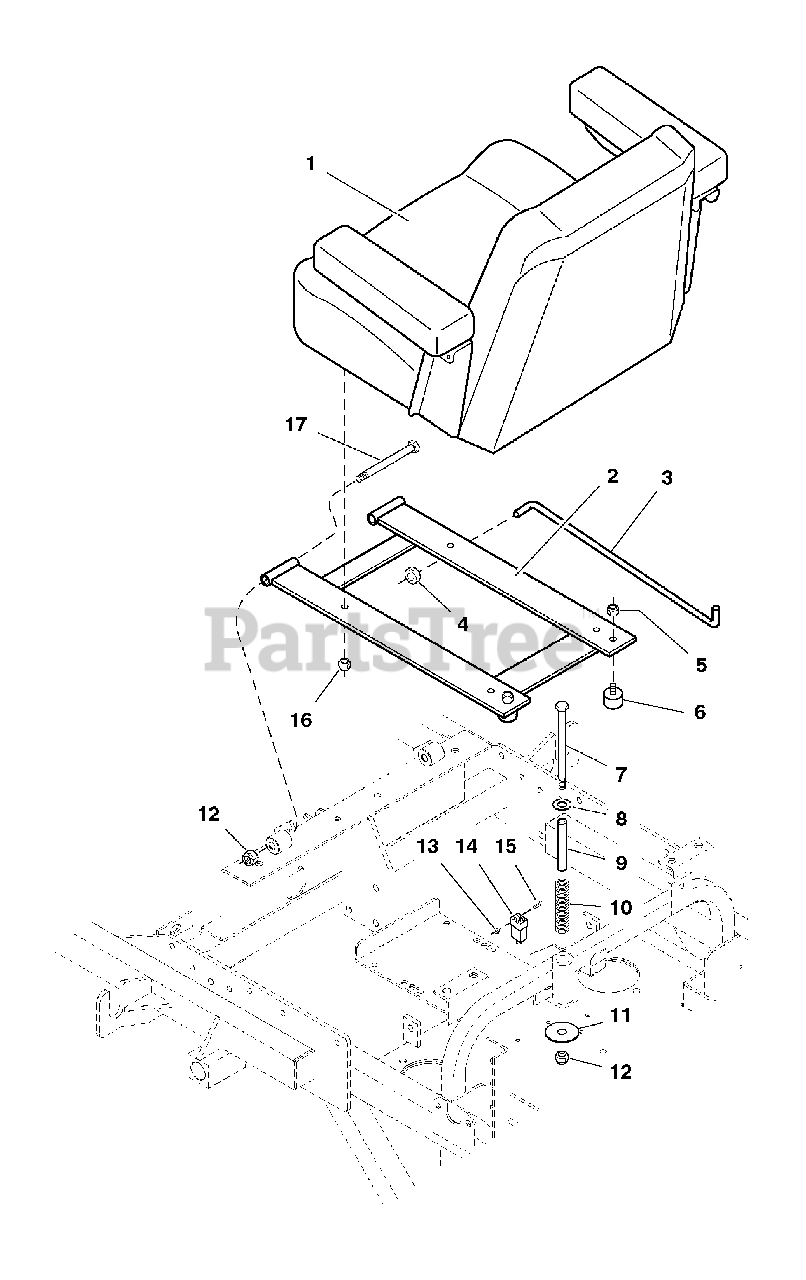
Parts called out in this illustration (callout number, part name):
1	SEAT, Brown (complete)
2	SEAT MOUNT
3	SEAT STOP ROD
4	COLLAR, 5/16 Set
5	NUT, Hex, Nylon Lock, 1/4-20
6	RUBBER BUMPER
7	CAPSCREW, Hex Hd, 3/8-16 x 6
8	WASHER, 3/8
9	SPACER, Seat Spring
10	SPRING, Compression
11	WASHER, 3/8 x 2
12	NUT, Hex, Nylon Lock, 3/8-16
13	NUT, Hex, #10-24
14	SWITCH, PLUNGER, N.O./N.C.
15	SCREW, #10-24 x 1
16	NUT, Hex, Nylon Lock, 5/16-18
17	CAPSCREW, Hex Hd, 3/8-16 x 4
